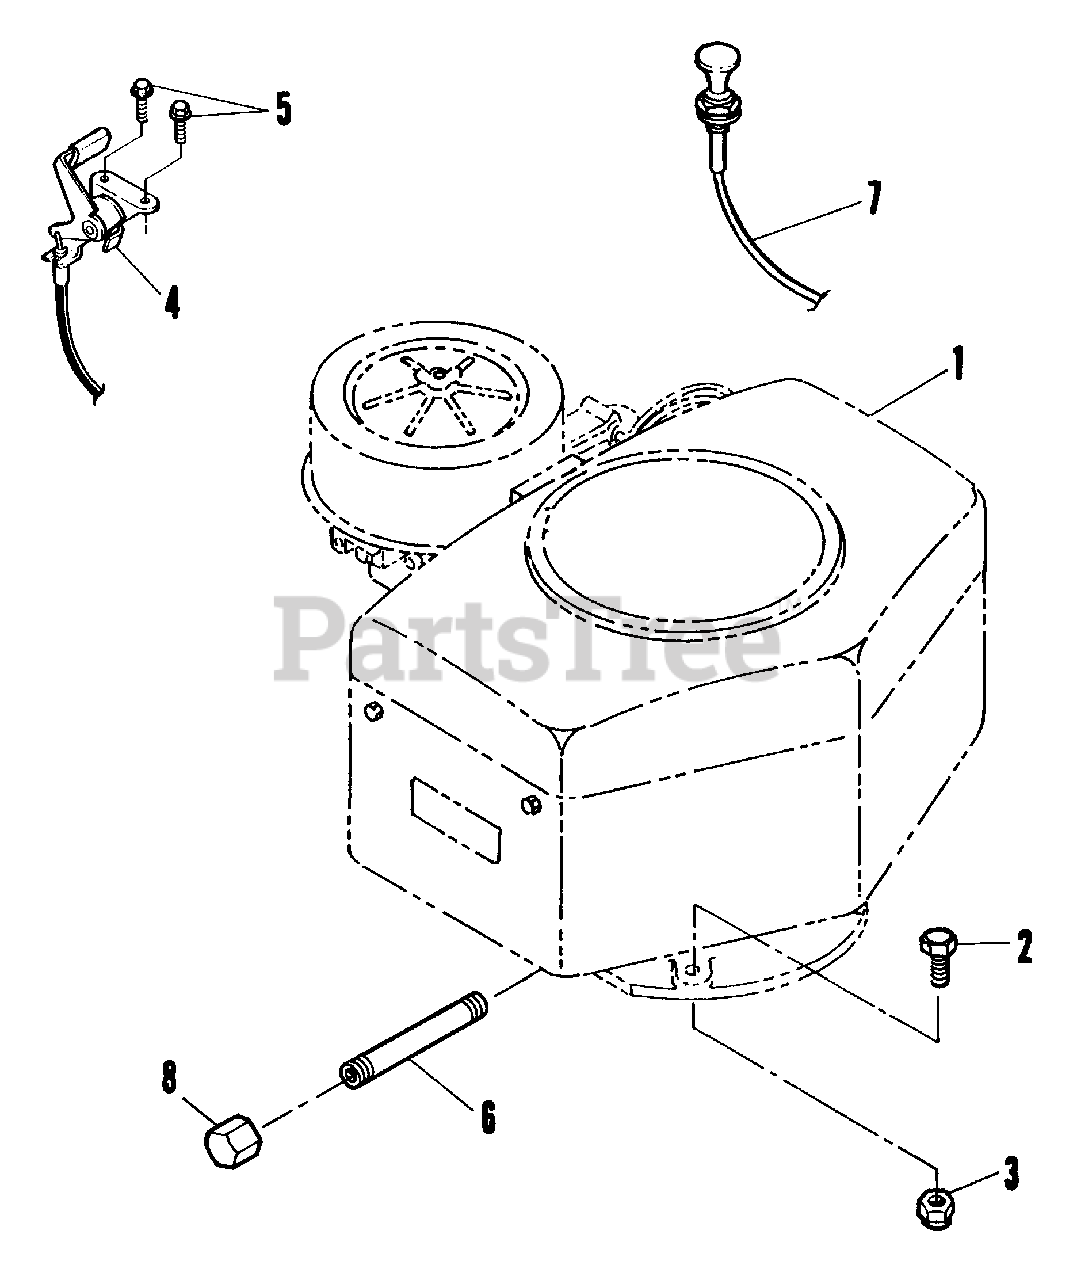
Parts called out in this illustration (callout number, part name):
2	SCREW, 5/16 C x 1 1/2, Hex Cap, Gr. 5
3	NUT, 5/16-18 Lock
4	THROTTLE, 18 H.P.Kohler
5	SCREW, #10-24 x 1/2" Hex Washer Self-Tap (Torx)
6	TUBE, Oil Drain
7	CHOKE ASSEMBLY
8	CAP, Oil Drain
